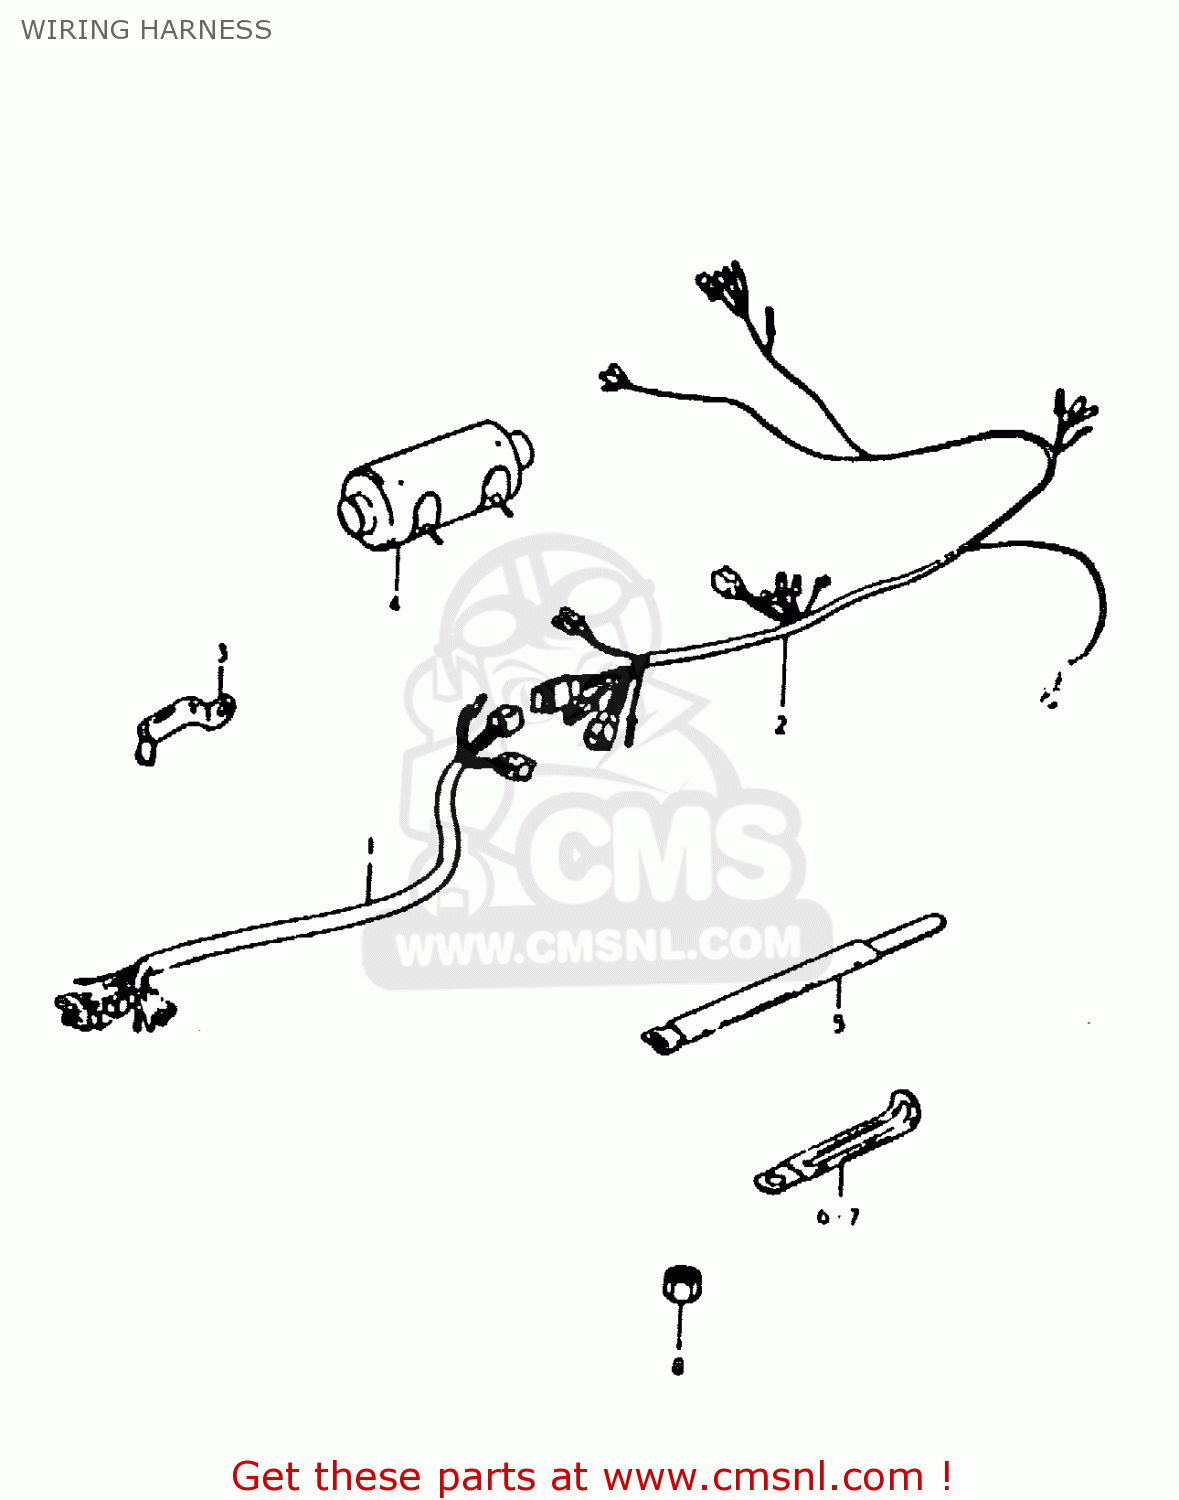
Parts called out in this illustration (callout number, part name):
1	WIRING HARNESS NO.1
2	WIRING HARNESS NO.2
3	CLAMP
4	BOOT,WIRING HARNESS
5	CLAMP
6	CLAMP
7	CLAMP
8	NUT
